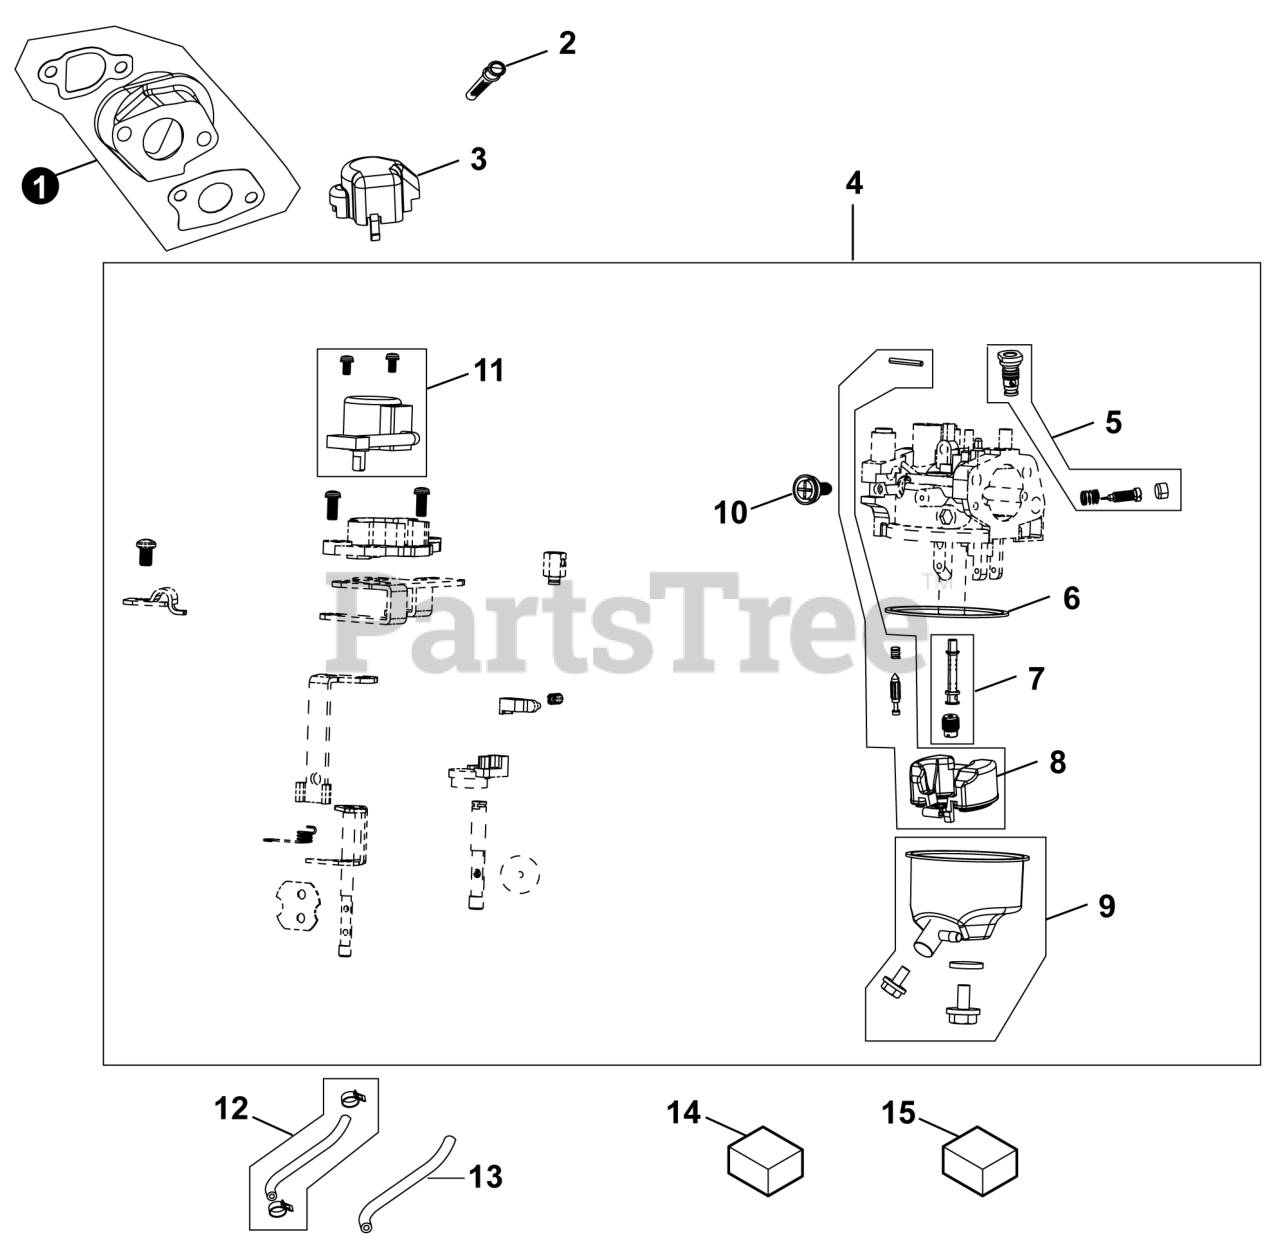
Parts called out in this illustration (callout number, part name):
1	SET, CARBURETOR GASKET
2	STRAINER?FUEL
3	CAP, STEPPER MOTOR
4	ASSY., CARBURETOR
5	KIT, IDLE SPEED JET
6	GASKET, FLOAT BOWL
7	KIT, MAIN JET
8	KIT, FLOAT/NEEDLE
9	KIT, CARBURETOR BOWL
10	SCREW, IDLE SPEED ADJUSTING
11	MOTOR, STEPPER
12	KIT, FUEL HOSE
13	HOSE, FUEL
14	KIT, HIGH ALTITUDE 3K-6K
15	KIT, HIGH ALTITUDE 6K-8K
